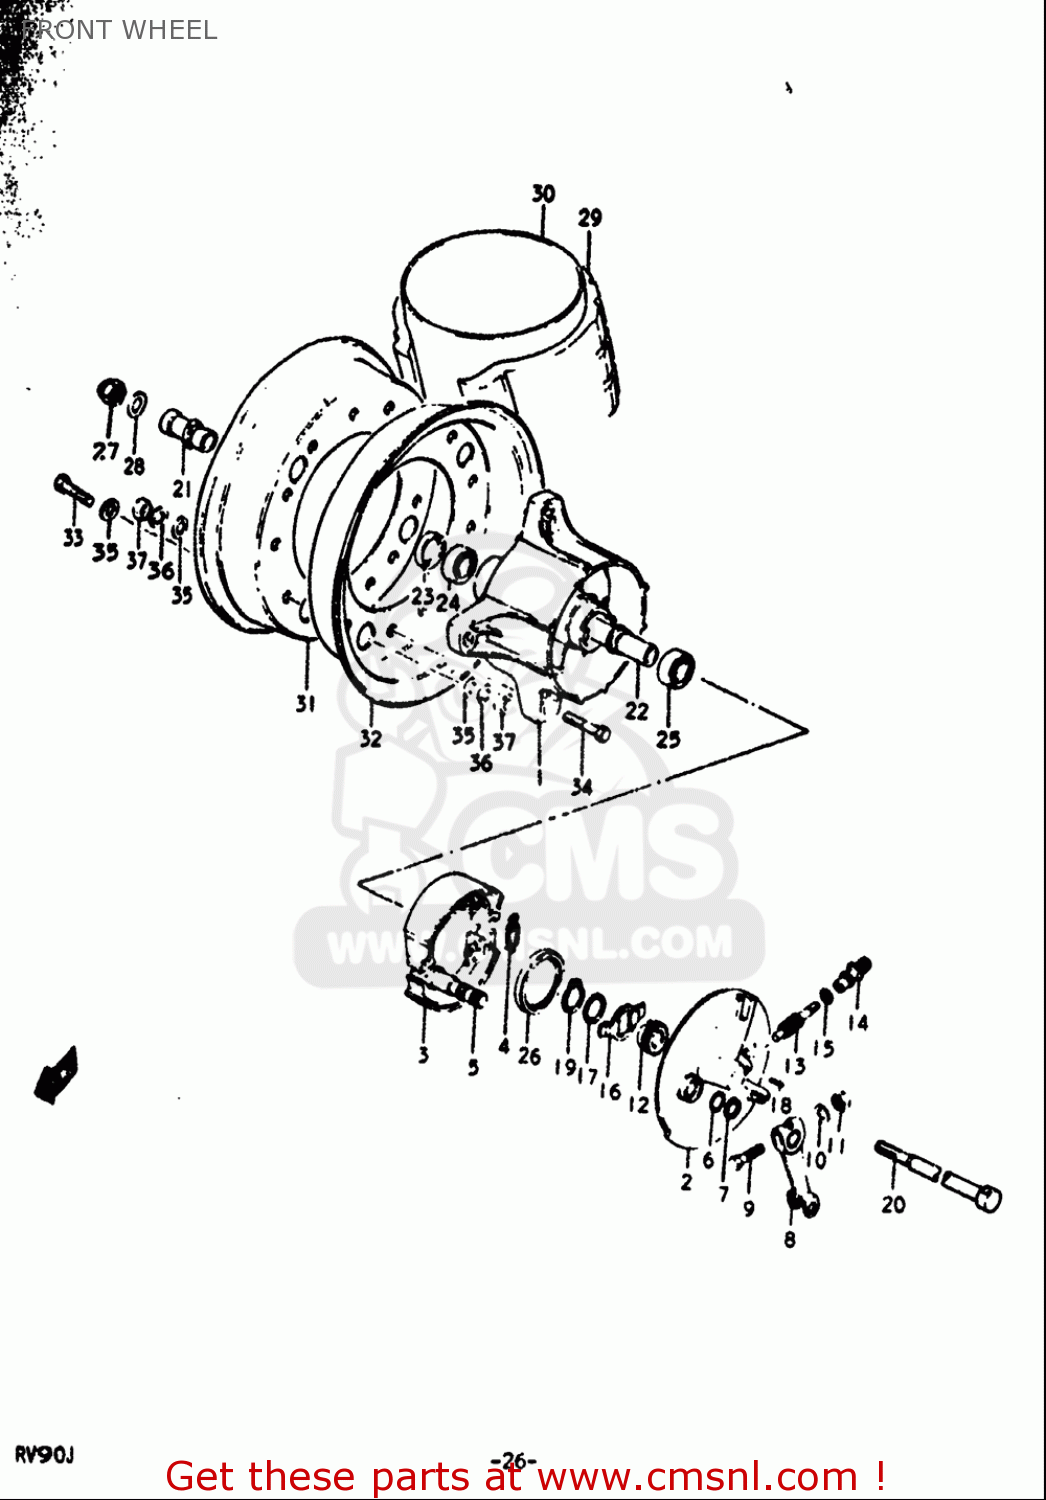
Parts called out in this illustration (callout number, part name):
3	SHOE & SPRING SET,BRAKE (NAS)
4	SPRING(L:35.8)
5	CAM,FR BRAKE
6	O RING(D:2.5,ID:11.4)
7	WASHER(12.5X20X1)
9	BOLT(6X31)
10	WASHER
11	NUT
12	GEAR,SPEEDOMETER
15	WASHER(5.1X9X0.4)
16	DRIVER,SPEEDOMETER GEAR
17	WASHER(18.5X24X1)
18	SCREW
19	CIRCLIP
20	AXLE,FRONT
23	FR HUB BRG OIL
24	BEARING
25	BEARING
26	SEAL,OIL(43X58X7)
27	NUT
28	WASHER
29	TIRE. (BRIDGESTONE)
30	TUBE,INNER
31	RIM,WHEEL RH
33	BOLT
34	BOLT
35	WASHER
36	WASHER,LOCK
37	NUT
